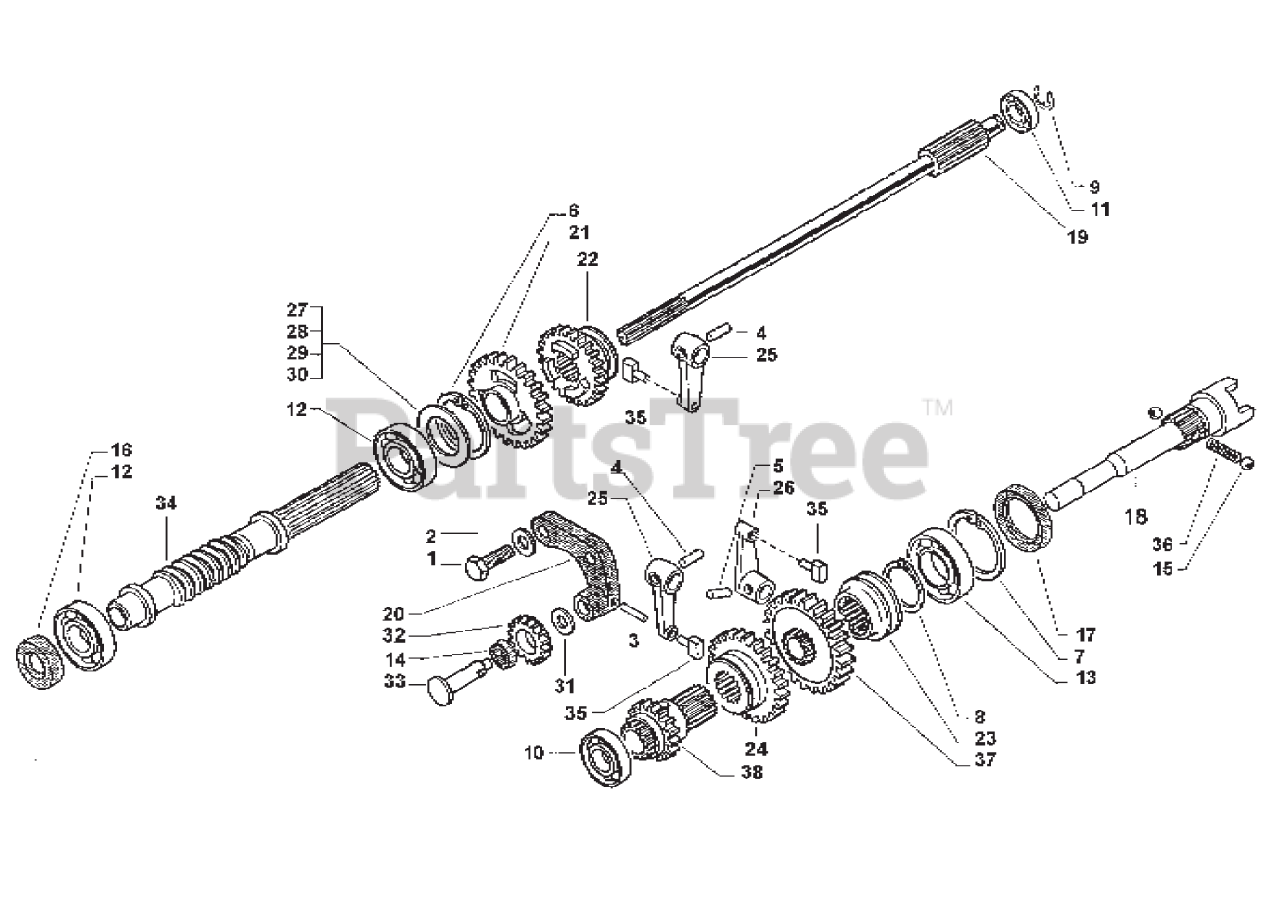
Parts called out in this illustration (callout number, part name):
1	SCREW, M1OX30
2	SUPER WASHER , M10
3	LOCKING PIN, M4X25
4	LOCKING PIN, M6X24
5	LOCKING PIN, M6X20 SPIRAL
6	CIRCLIP, INTERNAL
7	CIRCLIP, INTERNAL
8	CIRCLIP, EXTERNAL
9	RETAINING RING
10	BEARING, M15X35X11
11	BEARING, M15X42X13
12	BEARING, M25X52X15
13	BEARING, M30X55X13
14	BEARING, M12X15X10
15	BALL, 1/4"
16	OIL SEAL, M15X40X10
17	OIL SEAL, M38X55X7
18	PTO SHAFT
19	MAIN SHAFT
20	REVERSER BRACKET
21	FIRST GEAR
22	SLIDER GEAR
23	PTO SLIDER
24	SLIDER, REVERSER
25	LEVER, SLIDER
26	LEVER, PTO ENGAGEMENT
27	SHIM, 1.5MM
28	SHIM, 1.6MM
29	SHIM, 1.7MM
30	SHIM, 1.8MM
31	WASHER
32	REVERSE GEAR
33	PIN, REVERSE GEAR
34	WORM GEAR
36	SPRING, PTO BALLS
37	PTO GEAR
